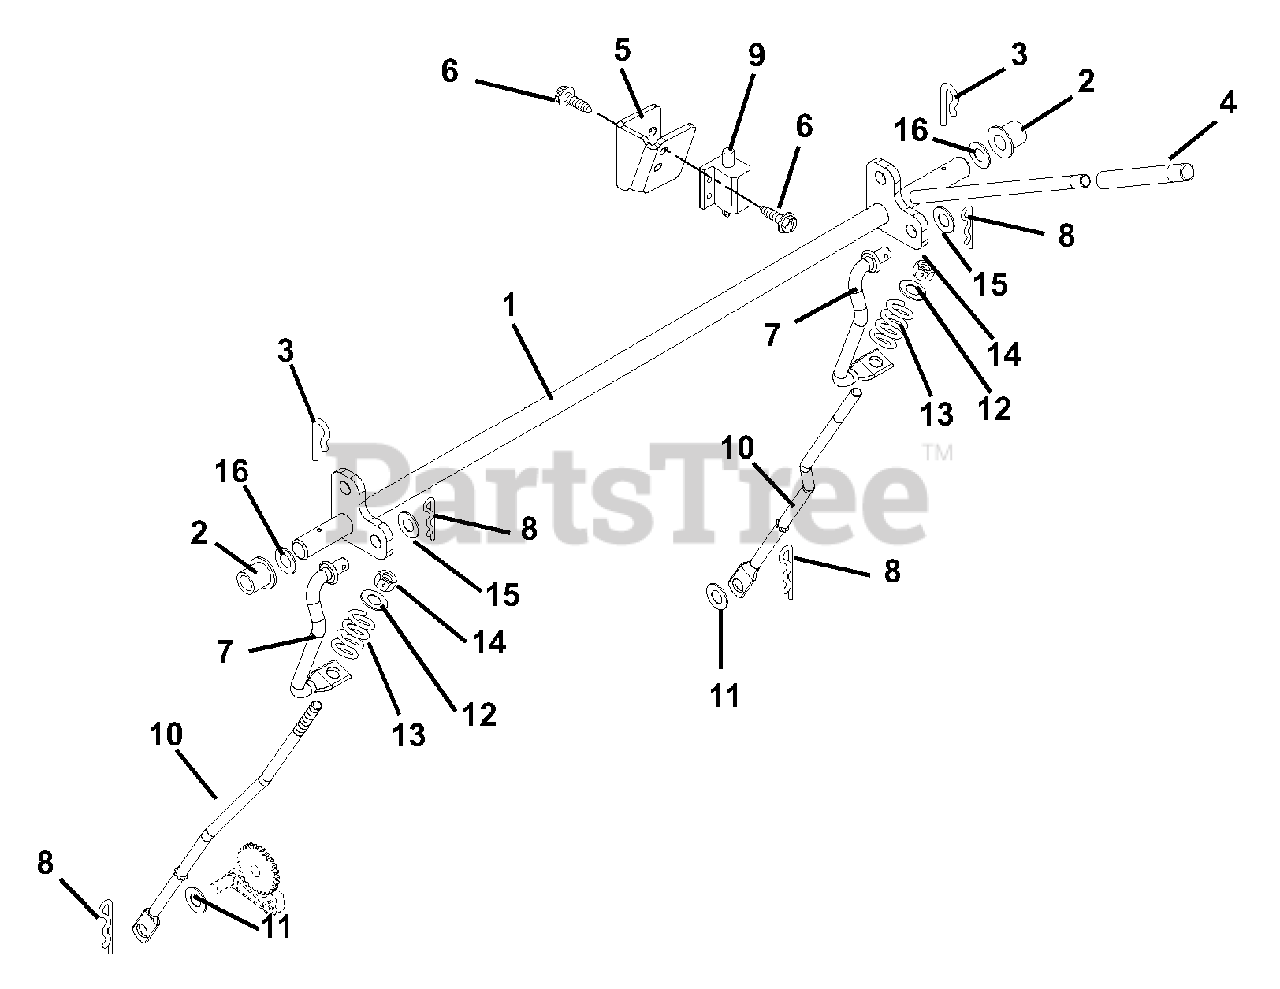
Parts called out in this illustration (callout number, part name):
1	WMT, PARKING BRAKE
2	BSHG-FLG .630X1.000X.625 NY
3	PIN, SPRING CLIP
4	GRIP,HAND CLUTCH LEVER
5	BRACKET, BRAKE SWITCH
6	@SCR-TAP 10-24X.50 HWH TR YWZC
7	ROD-OVER CENTER
8	PIN-HAIR, ENDRIES #25 YWZC
9	SWITCH,INTERLOCK
10	ROD-PARK BRAKE EZT
11	WSHR-FL-STL .406X1.00X.188 YWZ
12	@WSHR-FL-STL.344X.688X.065YWZC
13	SG-COMP .063X.53X1.187
14	@NUT-LK-NYL .312-18 YWZC
15	@WSHR-FL-STL.406X.812X.065 YWZ
16	WSHR-FL-STL .627X.990X.032
